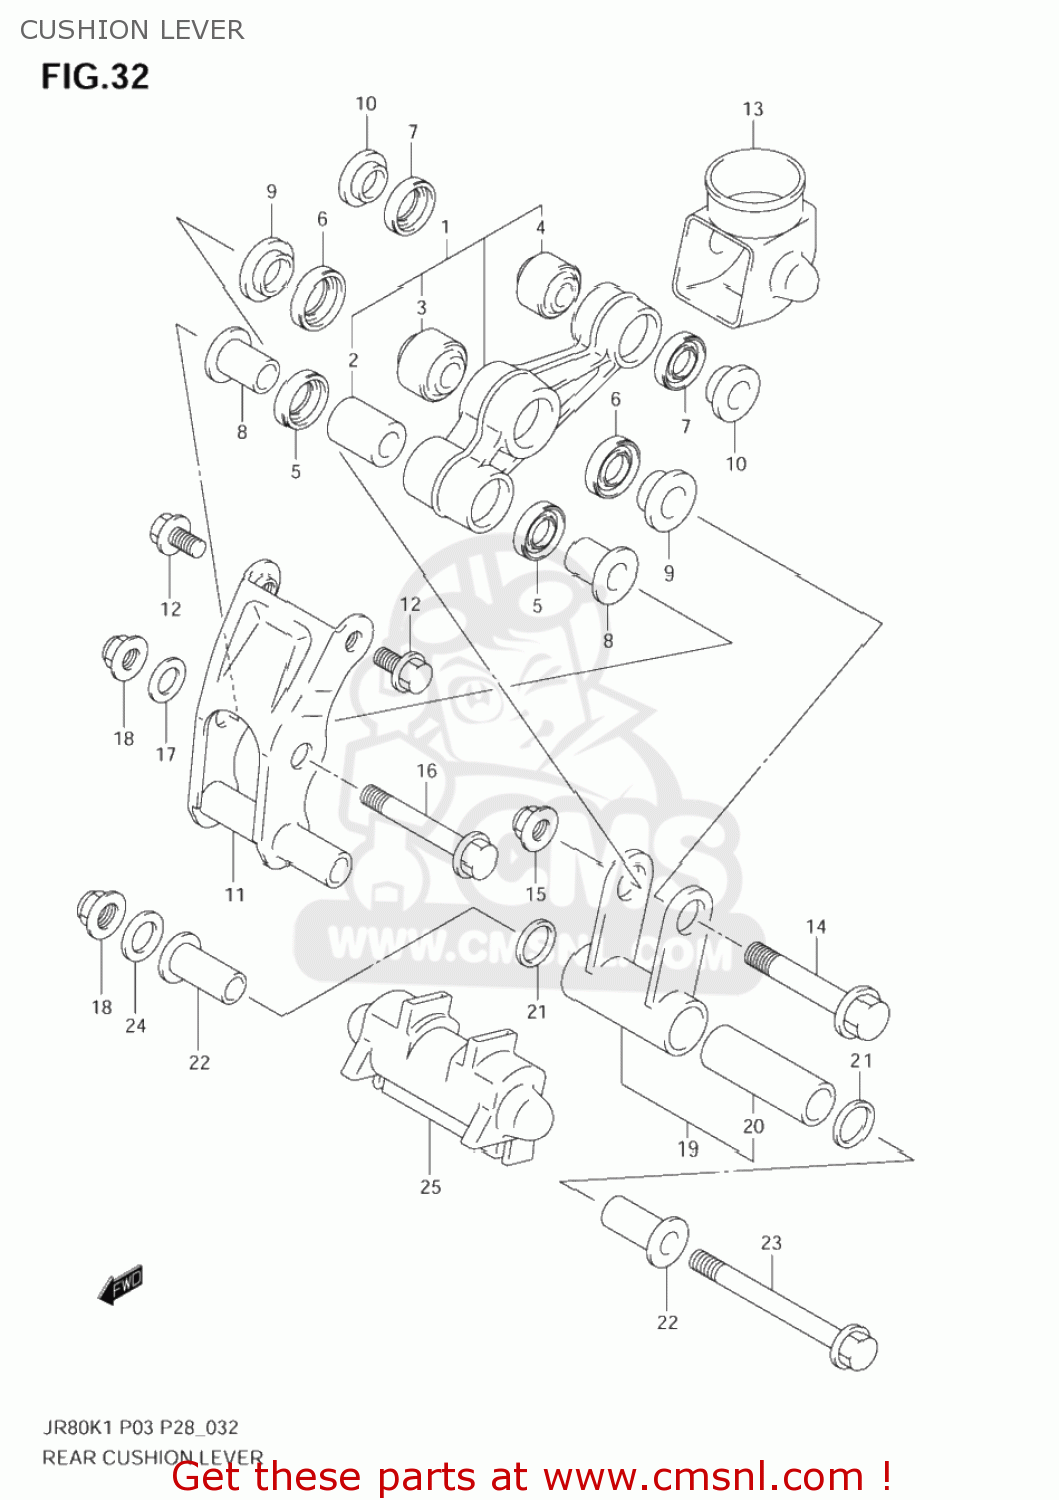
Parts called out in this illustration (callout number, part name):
1	LEVER SET,RR CUSHION
2	BUSHING,CUSHION FR(15X20X31)
3	BEARING(12X26X16)
4	BEARING(10X24X15)
5	DUST SEAL,RR CUSHION LEVER FR
6	DUST SEAL,RR CUSHION LEVER CTR
7	DUST SEAL,RR CUSHION LEVER RR
8	SPACER,RR CUSHION LEVER FR
9	SPACER
10	SPACER
11	HOLDER,RR CUSHION LEVER
12	BOLT,RR CUSHION LEVER HOLDER
13	BOOT,RR
14	BOLT(12X55)
15	NUT 12MM
16	BOLT(10X65)
17	WASHER(10.5X22X1.6)
18	NUT
19	LOD SET,RR CUSHION
20	BUSHING,LOD LWR(15X20X54)
21	DUST SEAL,LEVER CUSHION UNIT
22	SPACER,RR CUSHION ROD LWR
23	BOLT,RR CUSHION ROD LWR
24	WASHER(10.5X22X1.6)
25	BOOT,LWR
